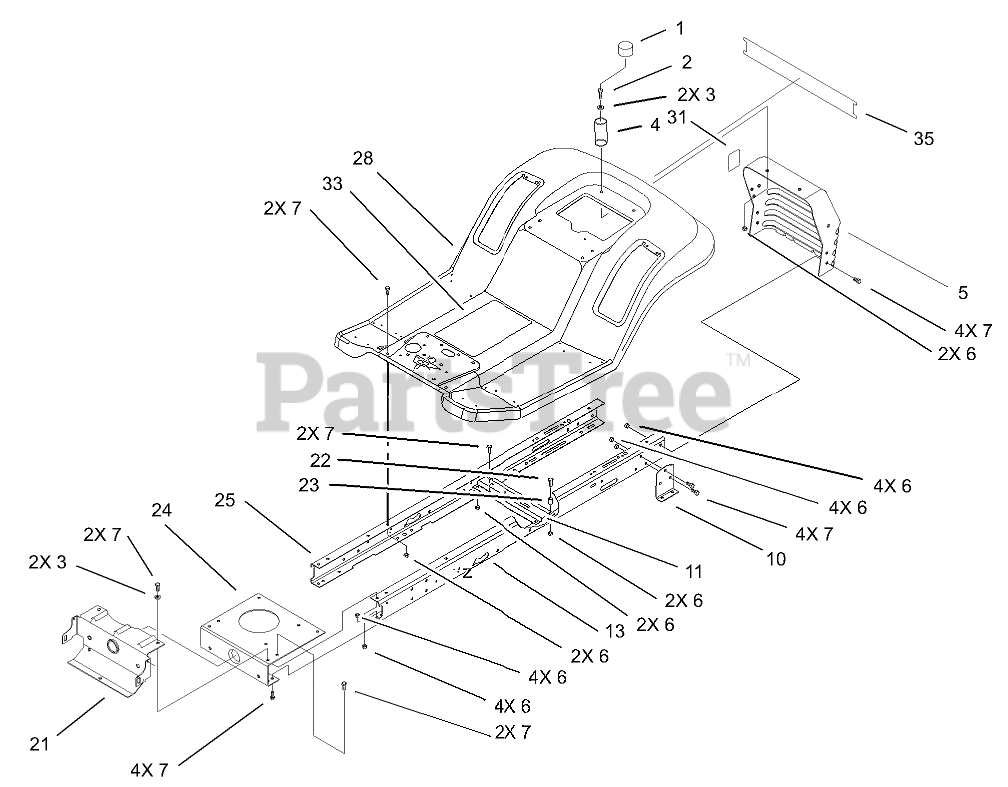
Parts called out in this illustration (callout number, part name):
1	CAP-PROTECTOR
2	SCREW-HH
3	WASHER-PLAIN
4	SPRING-COMPRESSION
5	SUPPORT-SEAT/REAR HITCH
6	NUT-LOCK, NI
7	SCREW-HH
10	BRACKET-TRANSAXLE, MOUNTING
11	BRACKET-IDLER PIVOT
13	RAIL-FRAME, LH
21	SUPPORT-FRONT, AXLE
22	SCREW-HH
23	SPACER
24	PLATE-MOUNTING, ENGINE
25	RAIL-FRAME, RH
28	REAR BODY ASM
31	DECAL-VALVE, DUMP
33	DECAL-INSTRUCTION
35	DECAL-REAR FENDER, LAWN TRACTORS
